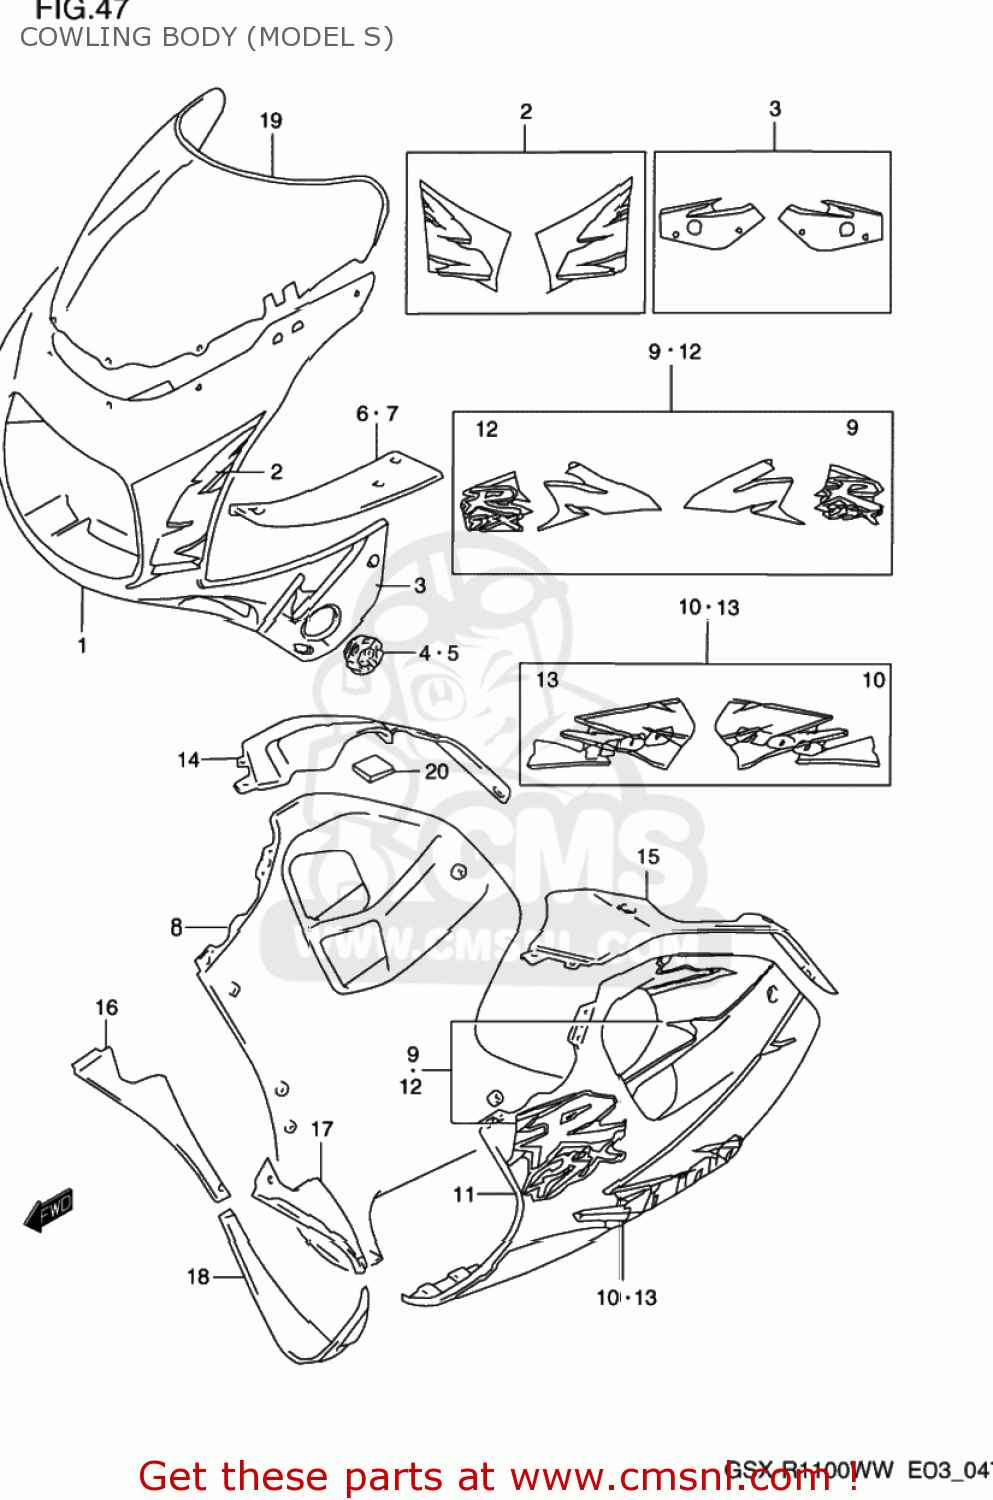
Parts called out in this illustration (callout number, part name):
1	COWLING ASSY,BODY
2	TAPE SET,COWL BODY FR
3	TAPE SET,COWLING BODY
4	PLATE,TURN SIGNAL,RIGHT
5	PLATE,TURNSIGNAL LAMP,L
6	PANEL,COWLING UPR,R
7	PANEL,COWLING UPR,L
8	COWLING ASSY,UNDER,R
9	TAPE SET,COWL UNDER,R
10	TAPE,COWL UNDER,R
11	COWLING ASSY,UNDER,L
12	TAPE SET,COWL UNDER,L
13	TAPE,COWL UNDER,L
14	PANEL,LWR,R
15	PANEL,LWR,L
16	COWLING,UNDER INNER,R
17	COWLING,UNDER INNER,L
18	COWLING,UNDER CTR
19	SCREEN SET,WINDOW
20	CUSHION,CHAIN CASE
